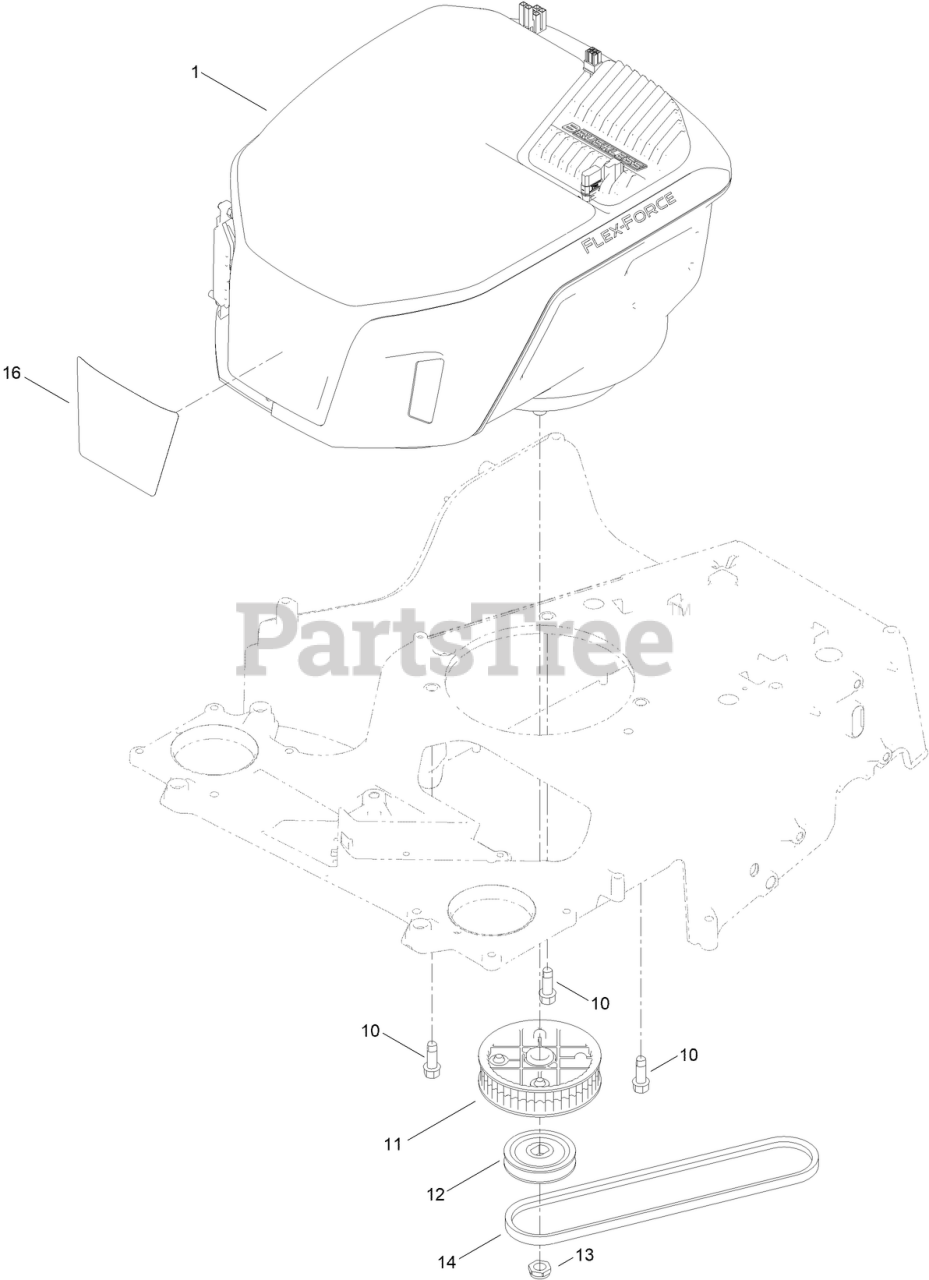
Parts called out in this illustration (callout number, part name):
1	MOTOR MODULE 60V
10	SCREW-THD FORM, HWH
11	SPROCKET
12	PULLEY-TRACTION
13	NUT-HEX JAM,NI
14	V-BELT, TRACTION
16	DECAL-60V
